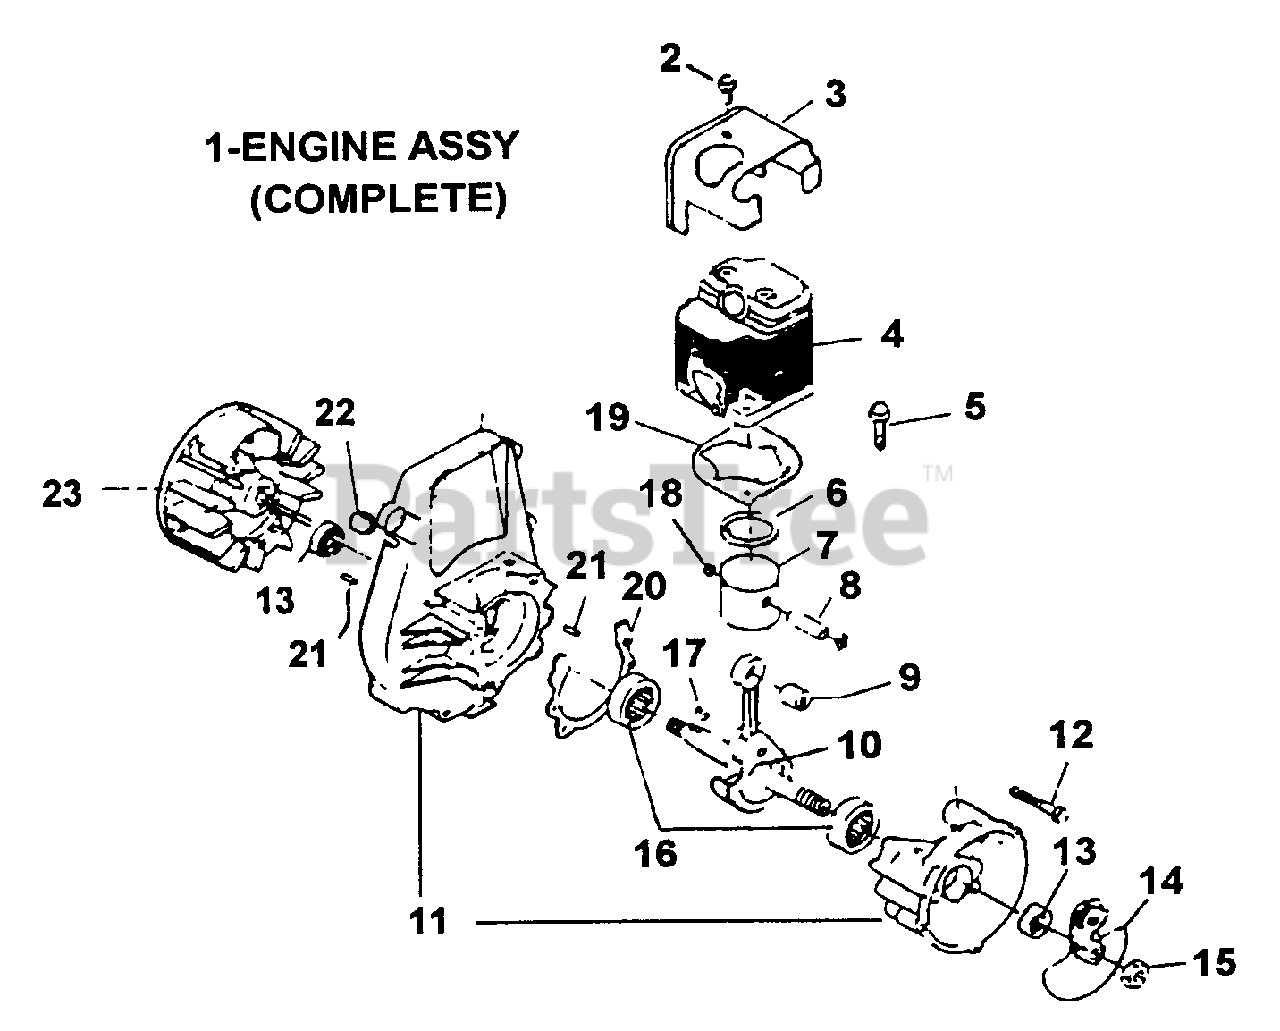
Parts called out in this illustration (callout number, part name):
1	ENGINE ASSY. (25cc)
3	COVER, CYLINDER
4	CYLINDER (25cc)
6	PIN, PISTON (25cc)
7	PISTON (25cc)
8	WRIST PIN (25cc)
10	CRANKSHAFT ASSY. (25cc)
11	CRANKCASE ASSY.
14	RATCHET ASSY. (25cc)
14	RATCHET ASSY. (21cc)
17	KEY, FLYWHEEL
18	SNAP RING
19	GASKET, CYLINDER
20	GASKET, CRANKCASE
